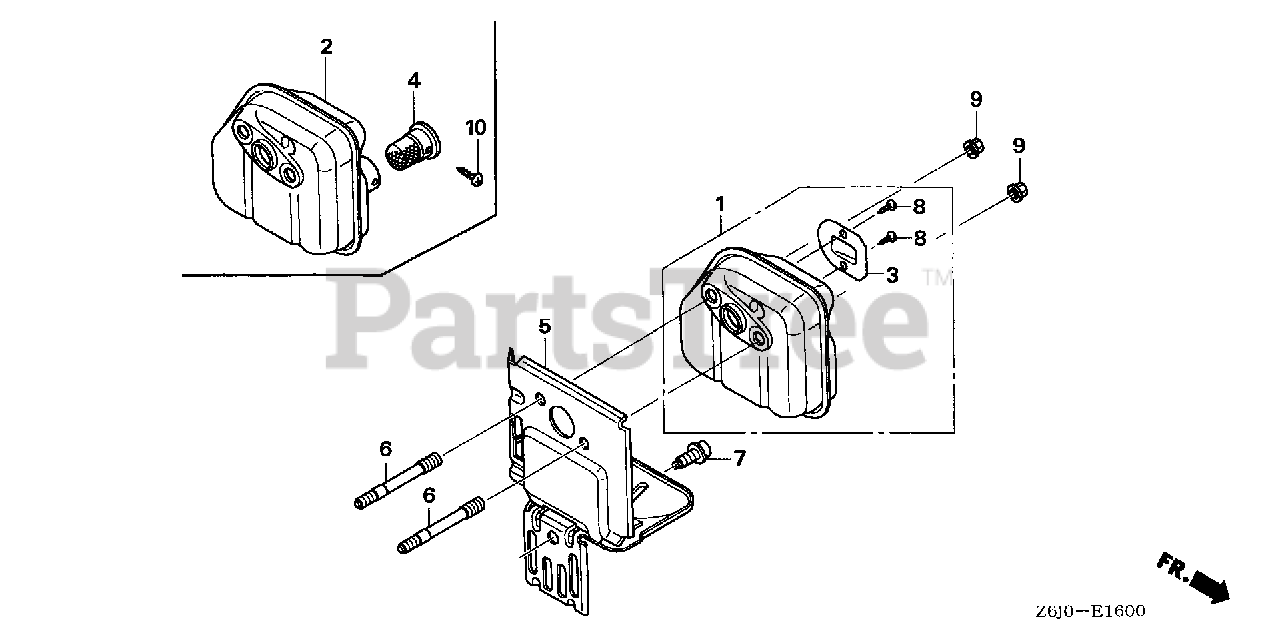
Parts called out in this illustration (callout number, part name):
3	ARRESTER, SPARK
5	GUIDE, AIR EX.
6	BOLT, STUD (5X52)
7	BOLT, SOCKET (5X10) (CT)
8	SCREW, TAPPING (4X6)
9	NUT, SELF-LOCK (5MM)
